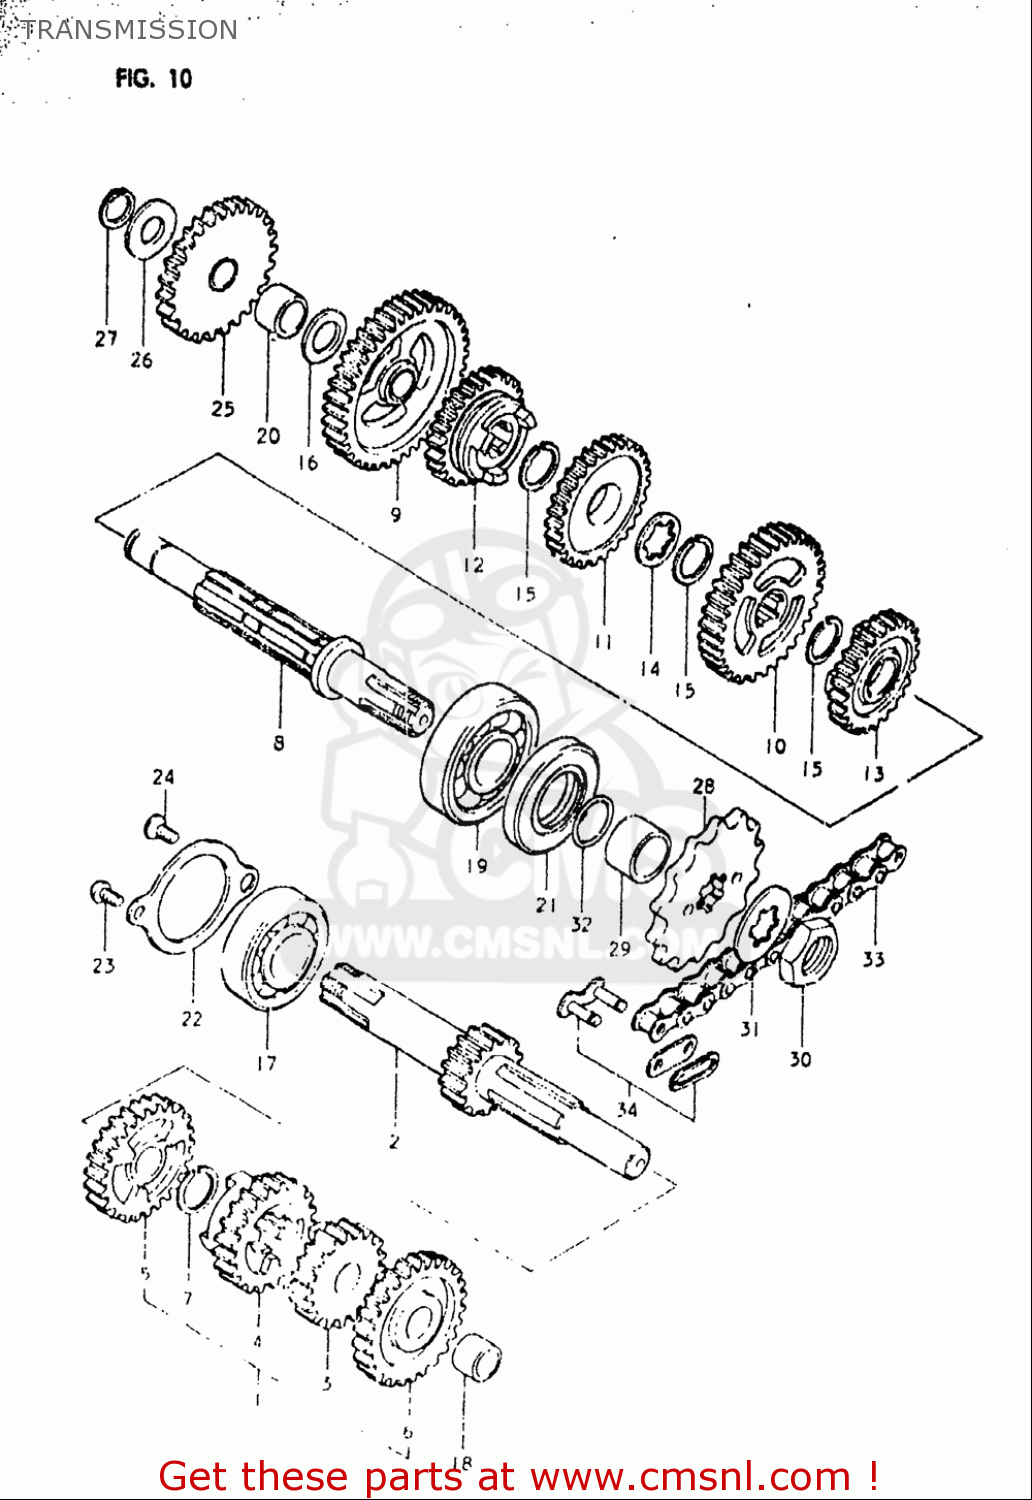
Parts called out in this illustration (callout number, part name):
2	SHAFT,COUNTER(NT:12)
4	GEAR,3RD DRIVE
5	GEAR,4TH DRIVE(NT:24)
6	GEAR,FIFTH DRIVE
7	CIRCLIP
8	SHAFT,DRIVE
10	GEAR,2ND DRIVEN(NT:33)
11	GEAR,3RD DRIVEN(NT:29)
12	GEAR,FOURTH DRIVEN
13	GEAR,5TH DRIVEN(NT:24)
14	WASHER(13X24X1)
15	CIRCLIP
16	WASHER,LOCK
17	BEARING(17X40X12)
18	BUSH
19	BEARING
20	BUSH
21	SEAL,OIL(21X40X6)
22	RETAINER,CNTR SHAFT BEARING
23	SCREW
24	SCREW
25	GEAR,KICK STARTER IDLE
26	WASHER
27	CIRCLIP,12 MM
28	SPROCKET,ENGINE
29	SPACER(17X21X13)
30	NUT
31	WASHER,LOCK
32	O RING(D:1,ID:16.8)
33	CHAIN,DRIVE(420X130L)
34	JOINT
